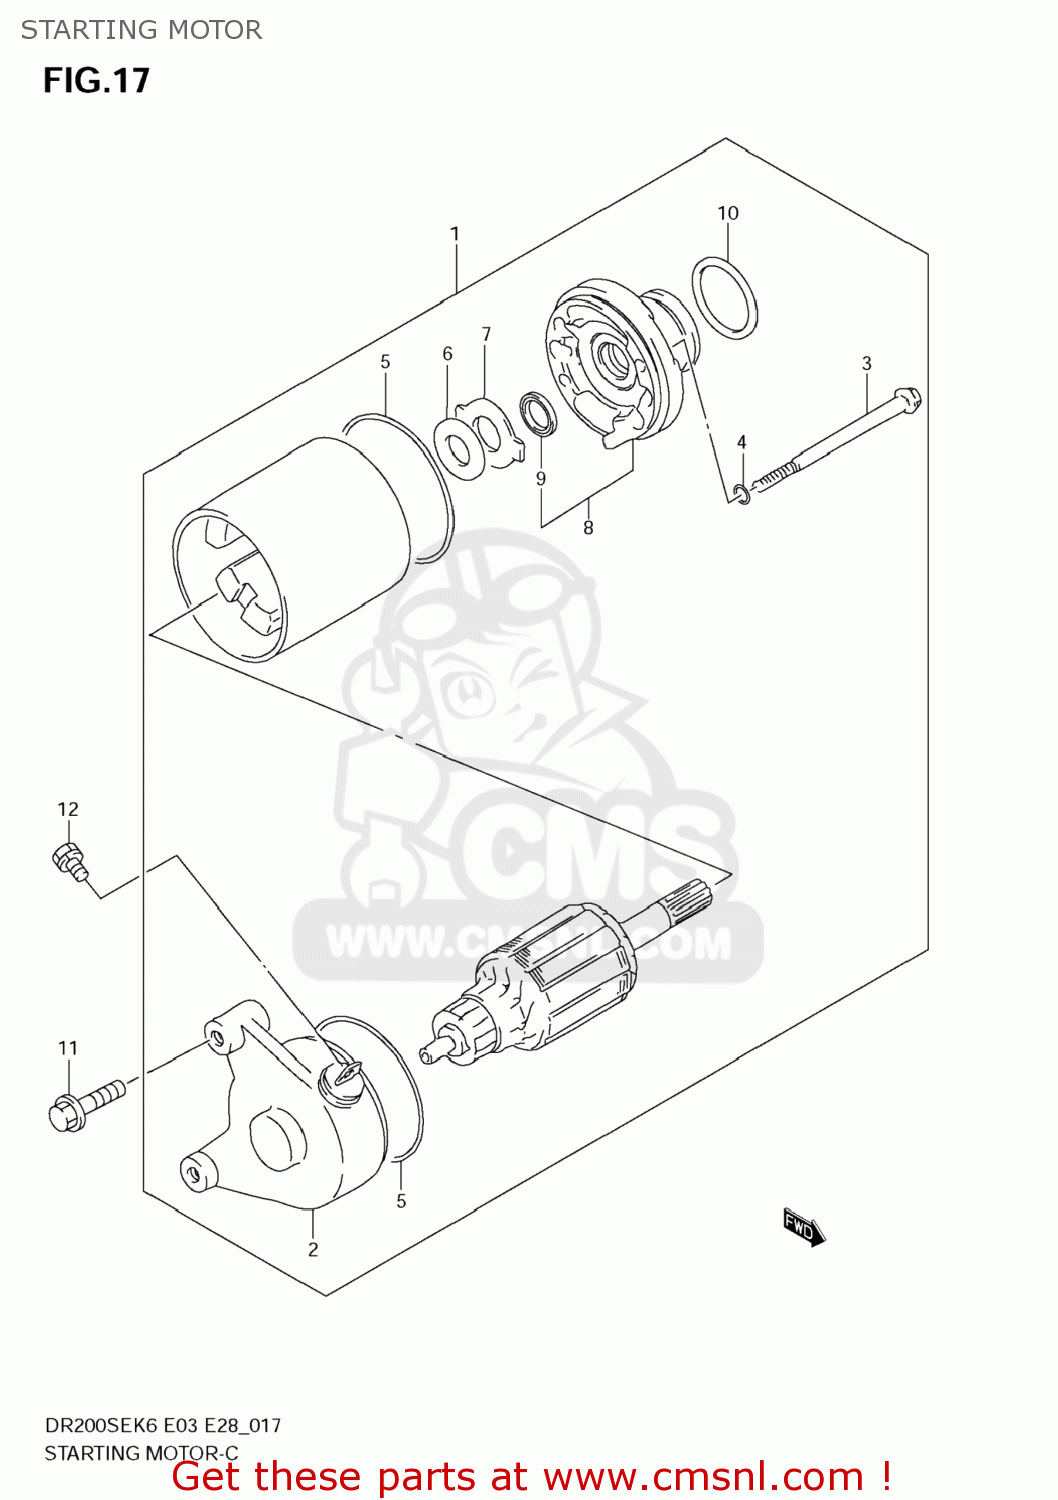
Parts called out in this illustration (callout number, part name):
1	MOTOR ASSY,STARTING
2	FRAME ASSY,COMMUTATOR END
3	BOLT
4	O RING
5	O RING
6	SHIM
7	PLATE,LOCK
8	BRACKET
9	SEAL,OIL
10	O RING(D:3,ID:24.5)
11	BOLT
12	SCREW(5X8)
